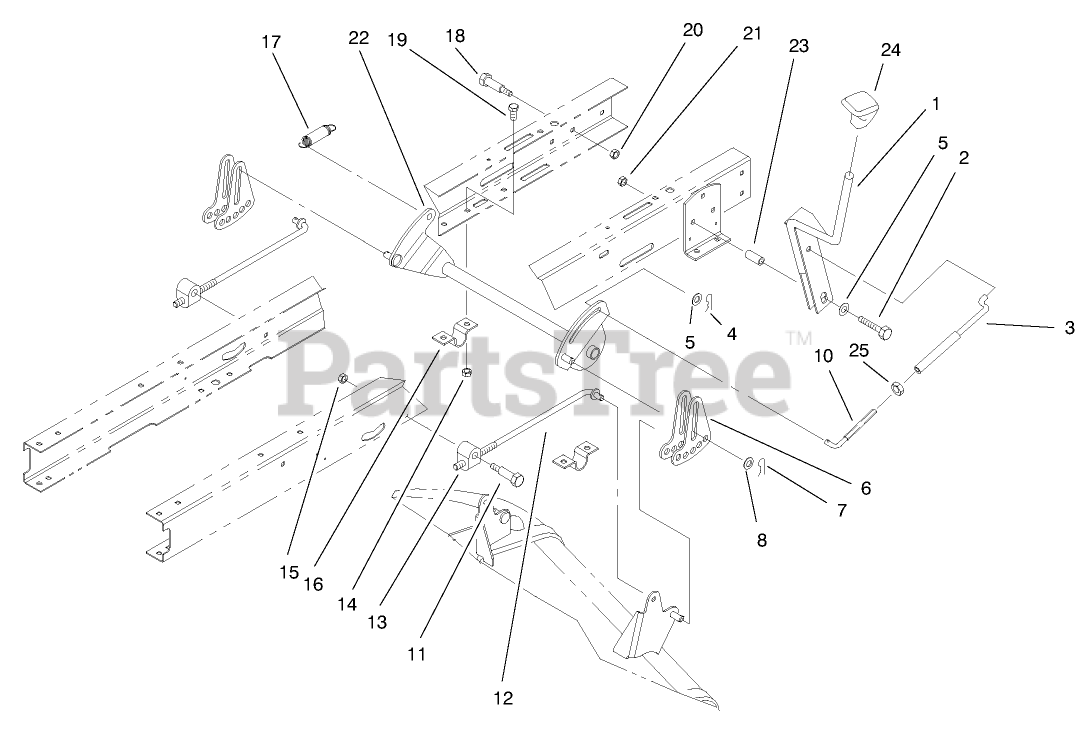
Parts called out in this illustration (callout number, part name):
2	SCREW-HH
3	HOC LINKAGE (WELDMENT)
5	WASHER-FLAT
6	LINK-ADJUSTING, HOC
8	WASHER-HARDENED
10	LINKAGE-HOC
11	SCREW-SHOULDER, HH
12	ROD-HANGER, REAR
13	TRUNNION-HOC
14	NUT-LOCK, NI
15	NUT-LOCK, NI
16	CLAMP-PIVOT, HOC
17	SPRING-EXTENSION
18	SCREW-SHOULDER, HH
19	SCREW-HH
20	NUT-LOCK, NI
21	NUT-LOCK, NI
22	HOC PIVOT ASM (BLACK)
23	SPACER
24	KNOB-SHIFT
25	NUT-JAM
